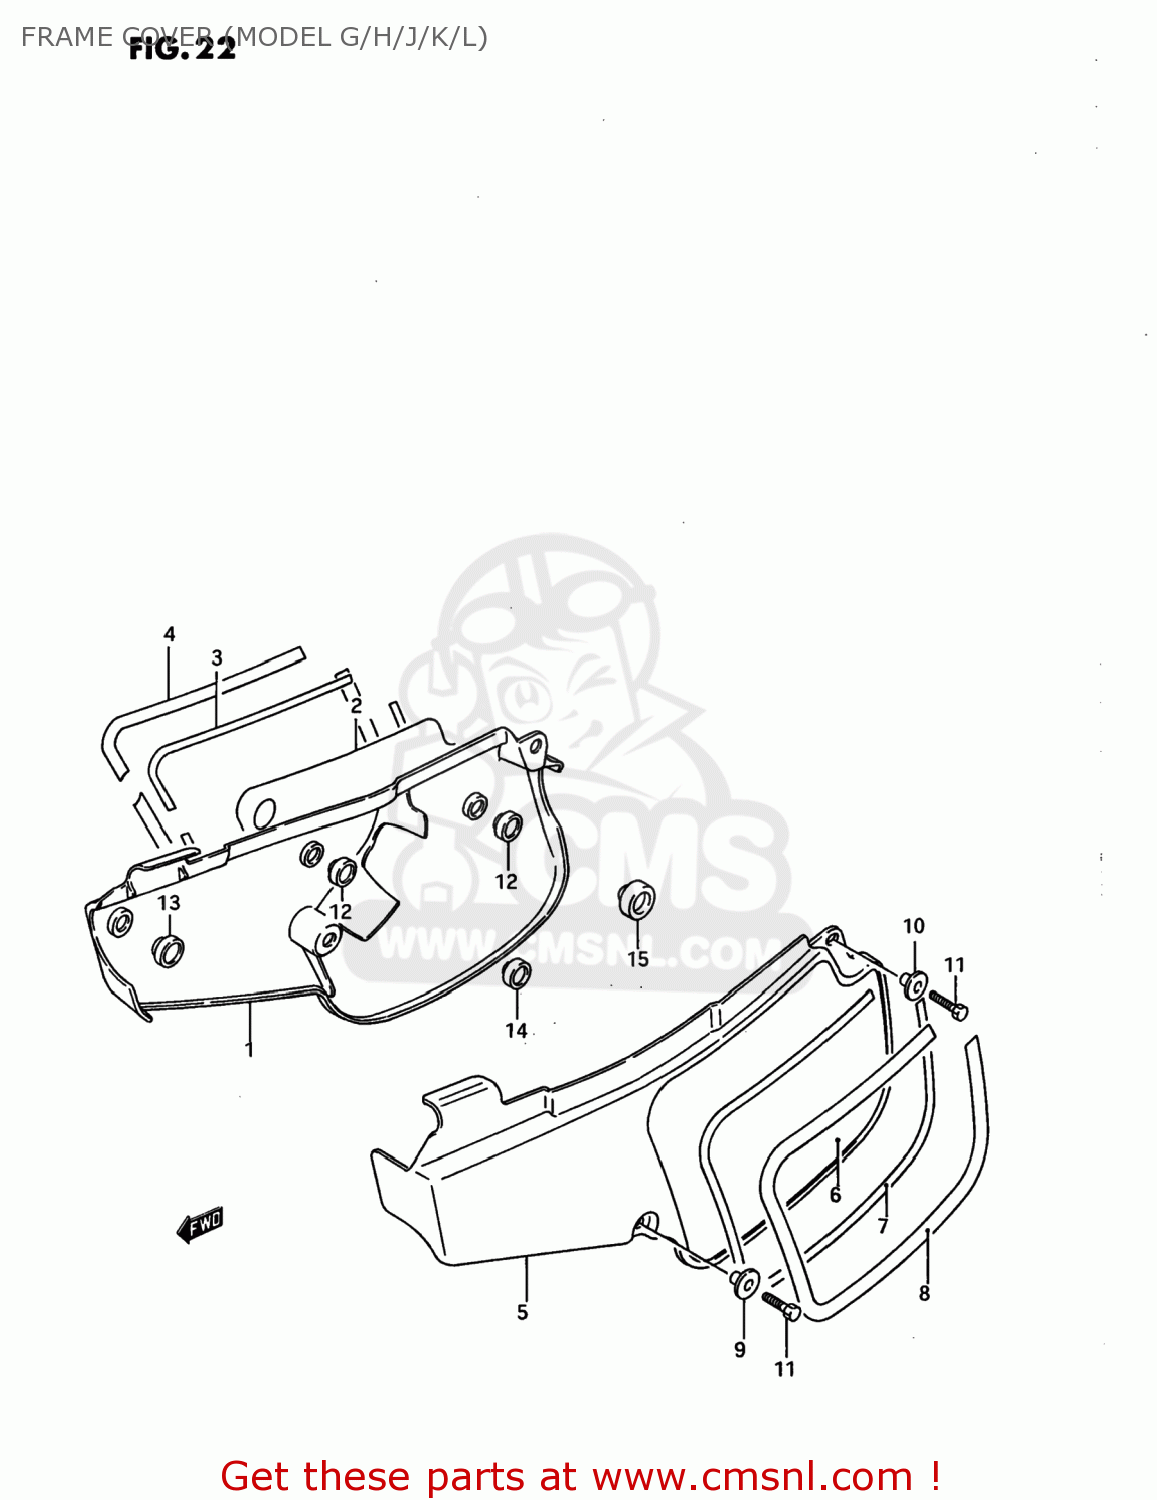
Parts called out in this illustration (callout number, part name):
1	COVER,FRAME,RIGHT
2	EMBLEM,FRAME COVER,RIGHT
3	EMBLEM,FRAME COVER,RIGHT
4	TAPE,FRAME COVER,RIGHT (BLUE)
5	COVER,FRAME,LEFT
6	EMBLEM,FRAME COVER,LEFT
7	EMBLEM,FRAME COVER,LEFT
8	TAPE,FRAME COVER,LEFT (BLUE)
9	WASHER
10	WASHER
11	BOLT
12	CUSHION
13	CUSHION
14	CUSHION
15	CUSHION
